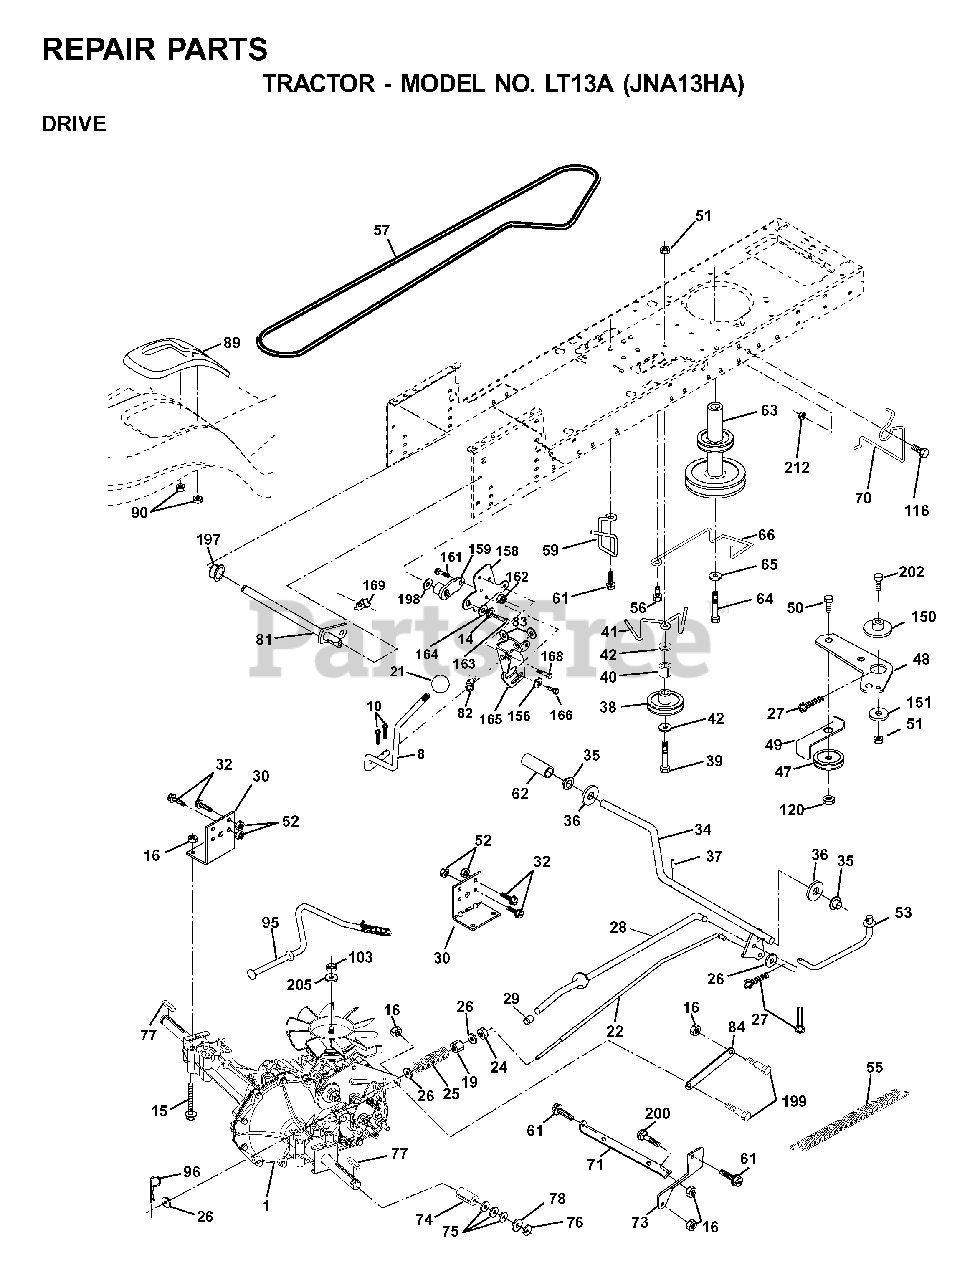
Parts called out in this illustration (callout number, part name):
8	ROD SHIFT FENDER ADJUST STLT
10	PIN COTTER
14	LOCKWASHER
15	BOLT HEX 5/16-18 GR 5
16	NUT.71038.31-18.HEX.NYLOCK
19	NUT
21	KNOB.DUCKHEAD.1/2
22	ROD BRAKE HYDRO
24	NUT
25	SPRING ROD LT
27	COTTER PIN
28	ROD, PARKING BRAKE
29	PLUNGER CAP
30	BRKT, MOUNT TRNSAXLE
32	BOLT
34	SHAFT, FOOT PEDAL
35	BEARING.NYLON
36	WASHER LT
37	DRIVE PIN
38	PULLEY.FLAT
39	BOLT
40	SPACER, SPLIT
41	KEEPER, BELT IDLER
42	WASHER
47	IDLER PULLEY
48	BELLCRANK, CLUTCH
49	RETAIN BELT
50	BOLT
51	LOCKNUT
52	LOCKNUT
53	LINK, CLUTCH LT
55	SPRING, RETURN LT
57	DRIVE BELT, LTH & YTH TRACTORS
59	KEEPER, BELT CENTER
61	SCREW 3/8-16X3/4
62	PEDAL COVER T
63	ENGINE PULLEY
64	BOLT
65	LOCKWASHER
66	KEEPER BELT ENGINE
70	KEEPER BELT ENG
71	STRAP TORQUE LH HYDRO
73	STRAP TORQUE RH HYDRO
74	SPACER AXLE
76	E-RING LT
77	SQUARE KEY
81	SHAFT ASM CROSS TAPERED
82	SHIFT SPRING
83	WASHER
95	CONTROL ASM. BYPASS HYDRO
96	RETAINER M
103	NUT.HEX.1/2-20
116	BOLT D
120	NUT LOCK FLG 3/8-16 UNC
150	SPACER, RETAINER
151	WASHER 12/32X2X10GA
156	WASHER.SRRTD.5/16
158	BRACKET
159	HUB
161	BOLT
162	NUT.CROWNLOCK.1/4
165	RP BRACKET
168	BOLT.SHOULDER.5/16-18X
169	PLATE.FASTENING.CROSS.SHAFT
197	NYLINER SNAP 5/8" ID
198	WASHER.NYL.7/8IDX.105"HYD CR
199	BOLT SHOULDER 5/16-18 UNC
200	BOLT
202	BOLT
205	WASHER
212	NUT
